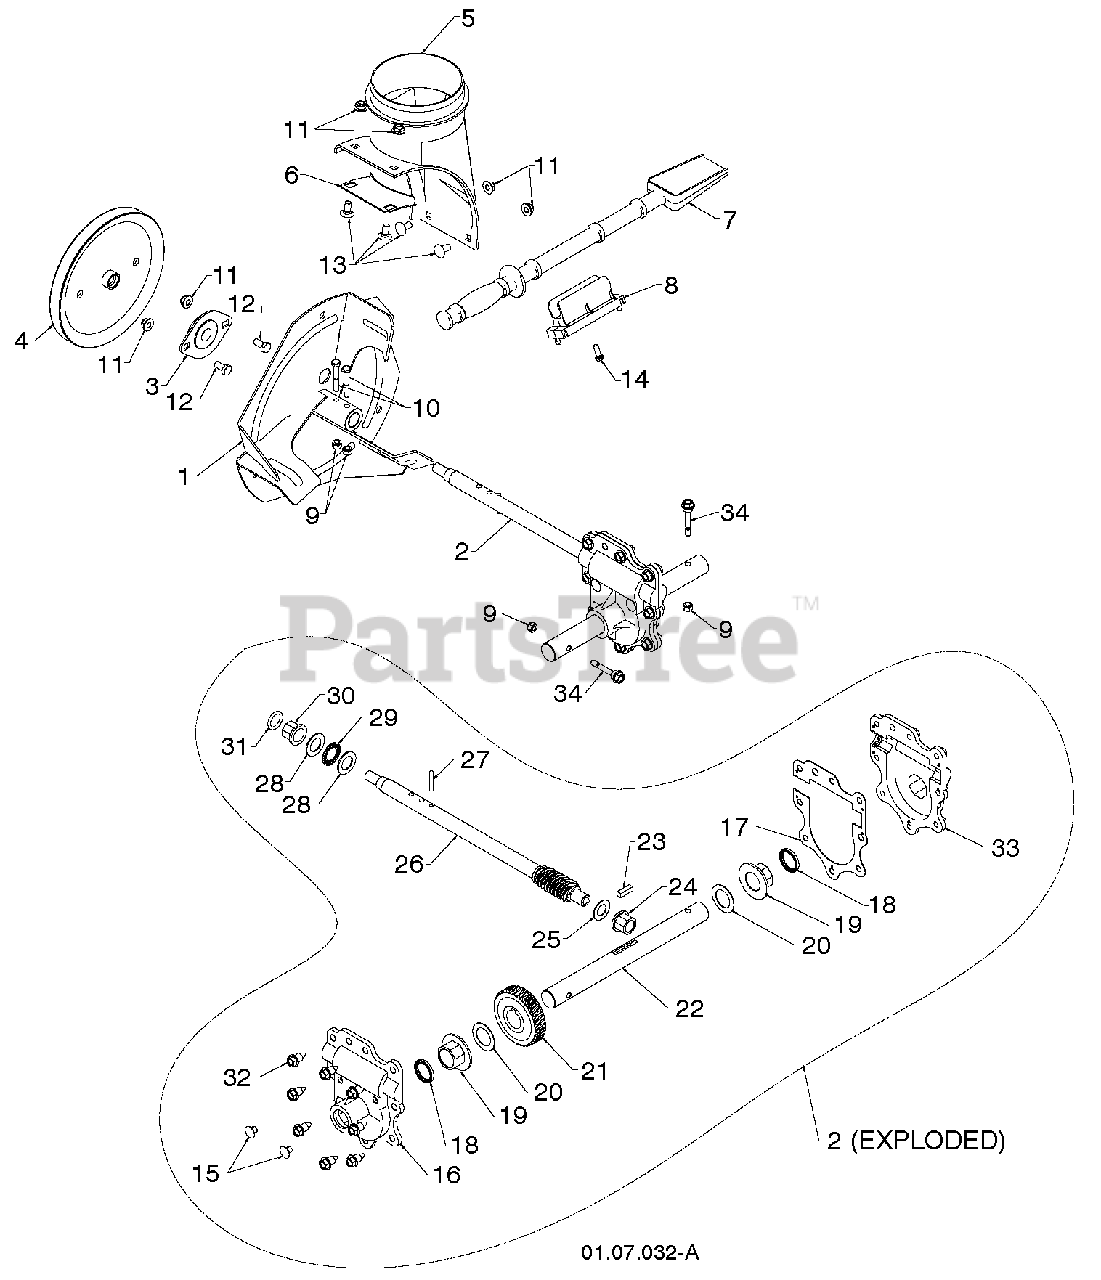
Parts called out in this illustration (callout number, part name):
1	IMPELLER ASSY
2	Gearcase/Pulley Kit
3	BEARING FLANGE
4	Impeller Pulley, 7.5" Screw-on
5	BASE.DISCHARGE.CHUTE
6	BRACKET, CORNER DISCHARGE
7	CLEAN OUT TOOL
8	CLIP.CLEANOUT.TOOL
9	LOCKNUT
10	SCREW.HEX.HD1/4-20X
11	NUTNYLOK.FLRANGE.5/16-18
12	BOLT, HEX HEAD 5/16-18
13	BOLT.CARRIAGE.5/16-18X
14	SCREW.HWH.13-16-5.8.BZP
15	CASE PLUG
16	GEAR.BOX.COVER.RIGHT.SIDE
17	GASKET.GEAR.BOX
18	OIL SEAL
19	FLANGE BUSHING-1"
20	WASHER TRUST 1"
21	WORM GEAR
22	AUGER SHAFT
23	KEY, SQUARE 1/4 X .875
24	FLANGE BUSHING-5/8
25	WASHER, THRUST 5/8
26	Gearcase/Pulley Kit
27	PIN, ROLL 3/16 X 1-1/8
28	WASHER, THRUST 3/4
29	BEARING TRUST 3/4
30	BUSHING, FLANGE 3/4
32	HEX SCREW-5/16 X 3/4
33	GEAR.BOX.COVER.LEFT.SIDE
34	BOLT, SHOULDER SHEAR
